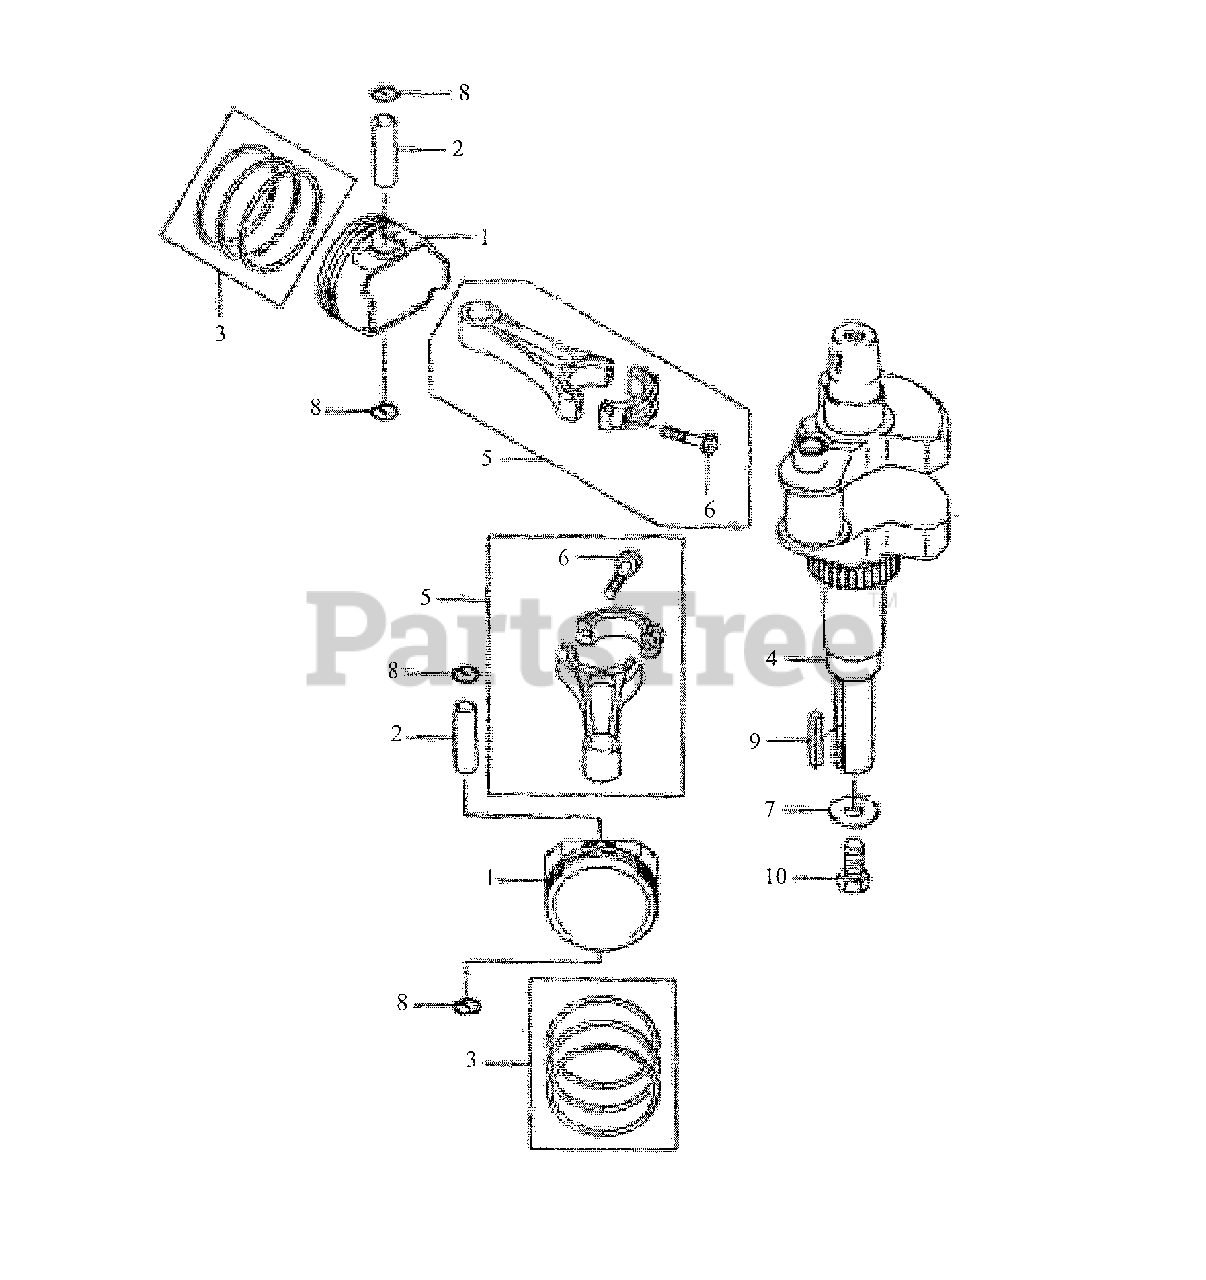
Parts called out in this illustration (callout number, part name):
1	Piston-Engine
3	Ring-Set-Piston
4	S Crankshaft Complete
5	S Rod-Connecting
7	Washer, 12.5x32x3.2
10	Bolt,7/16-20unf
